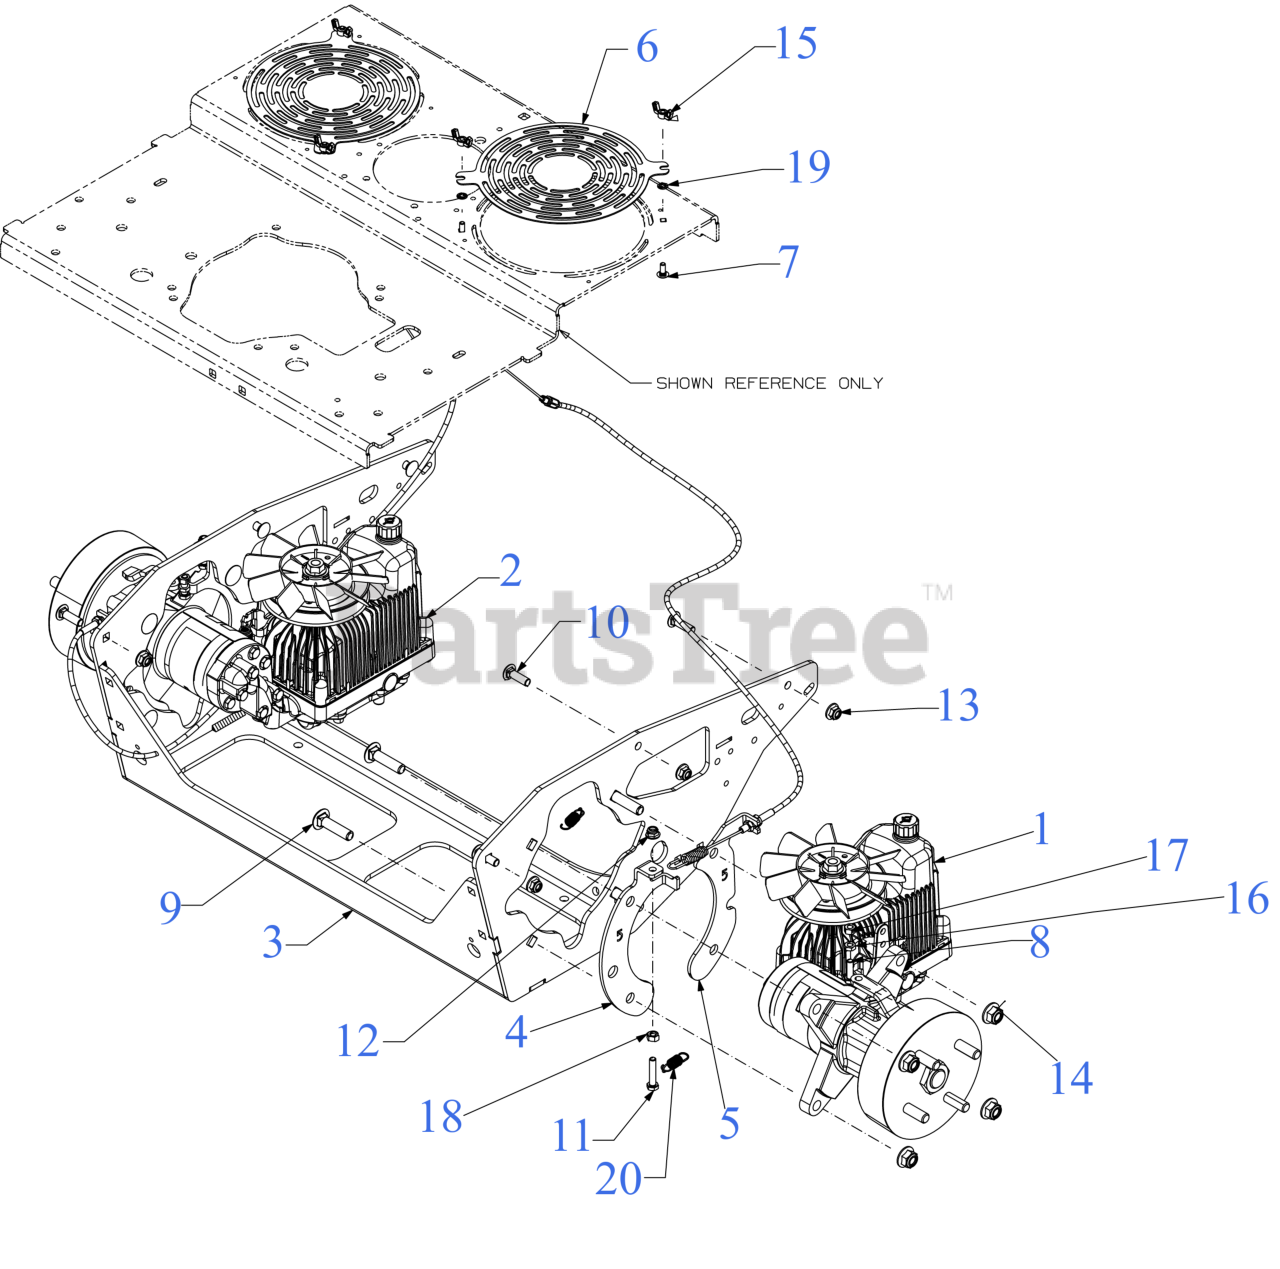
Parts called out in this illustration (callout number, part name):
1	TRANSMISSION/MOTOR ASM RH
2	TRANSMISSION/MOTOR ASM LH
3	TRANSMISSION MOUNTING BRACKET
6	TRANSMISSION COVER PLATE
7	CARRIAGE BOLT 1/4-20 x .62
8	SCREW 5/16-18 x 1.0 GR5
9	CARRIAGE BOLT 1/2-13 GR5
10	CARRIAGE BOLT 3/8-16 X1.25 GR5
11	SCREW 5/16-18 x 1.5 LG
12	FLANGE LOCK NUT 5/16-18
15	WING NUT 1/4-20
18	HEX NUT 5/16-18
19	RETAINER-BOLT .25ID x .50OD
20	EXTENSION SPRING .500 OD x 1.71
